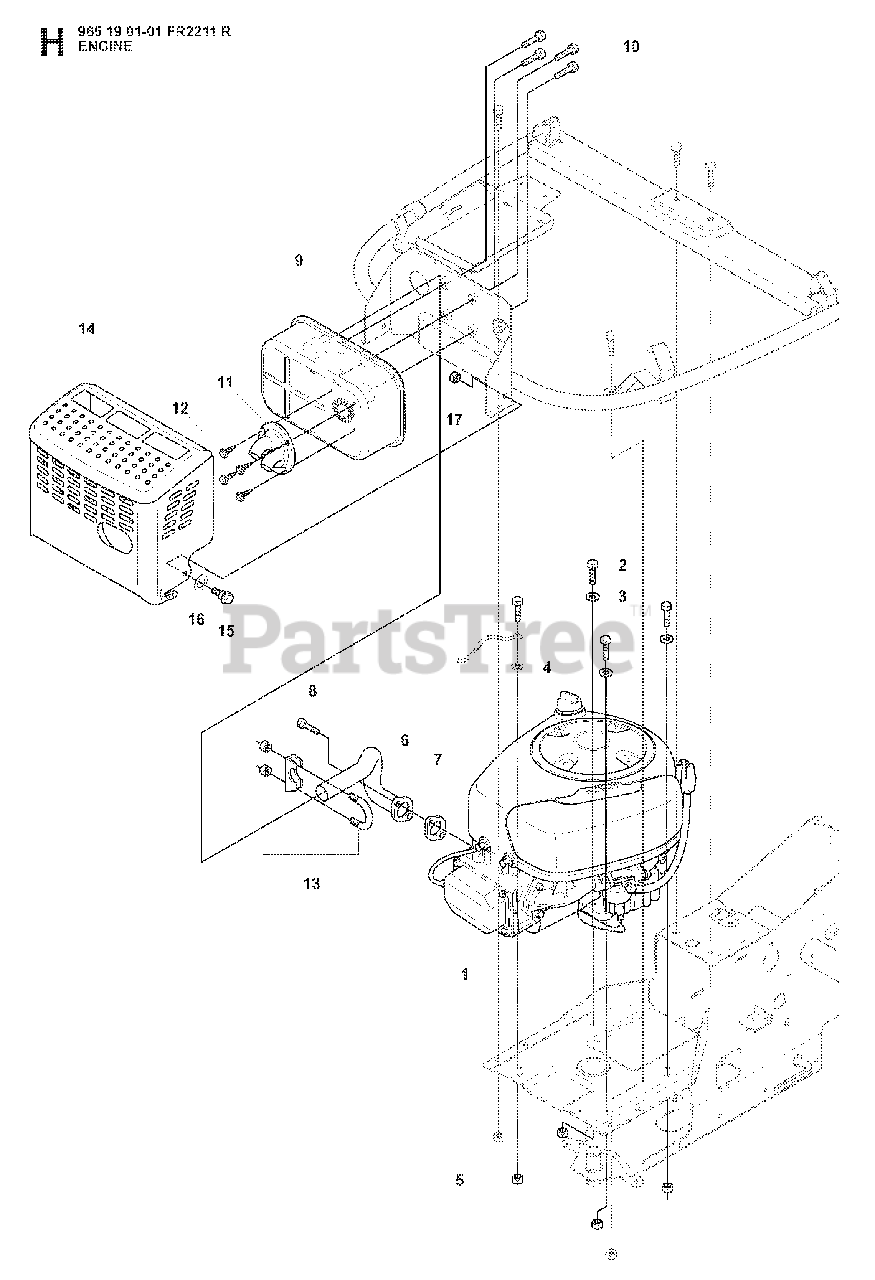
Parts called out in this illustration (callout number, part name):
3	WASHER BRB 8.4X17
5	LOCKNUT M8
9	MUFFLER
16	SPRINGWASHER
17	LOCKNUT M8
